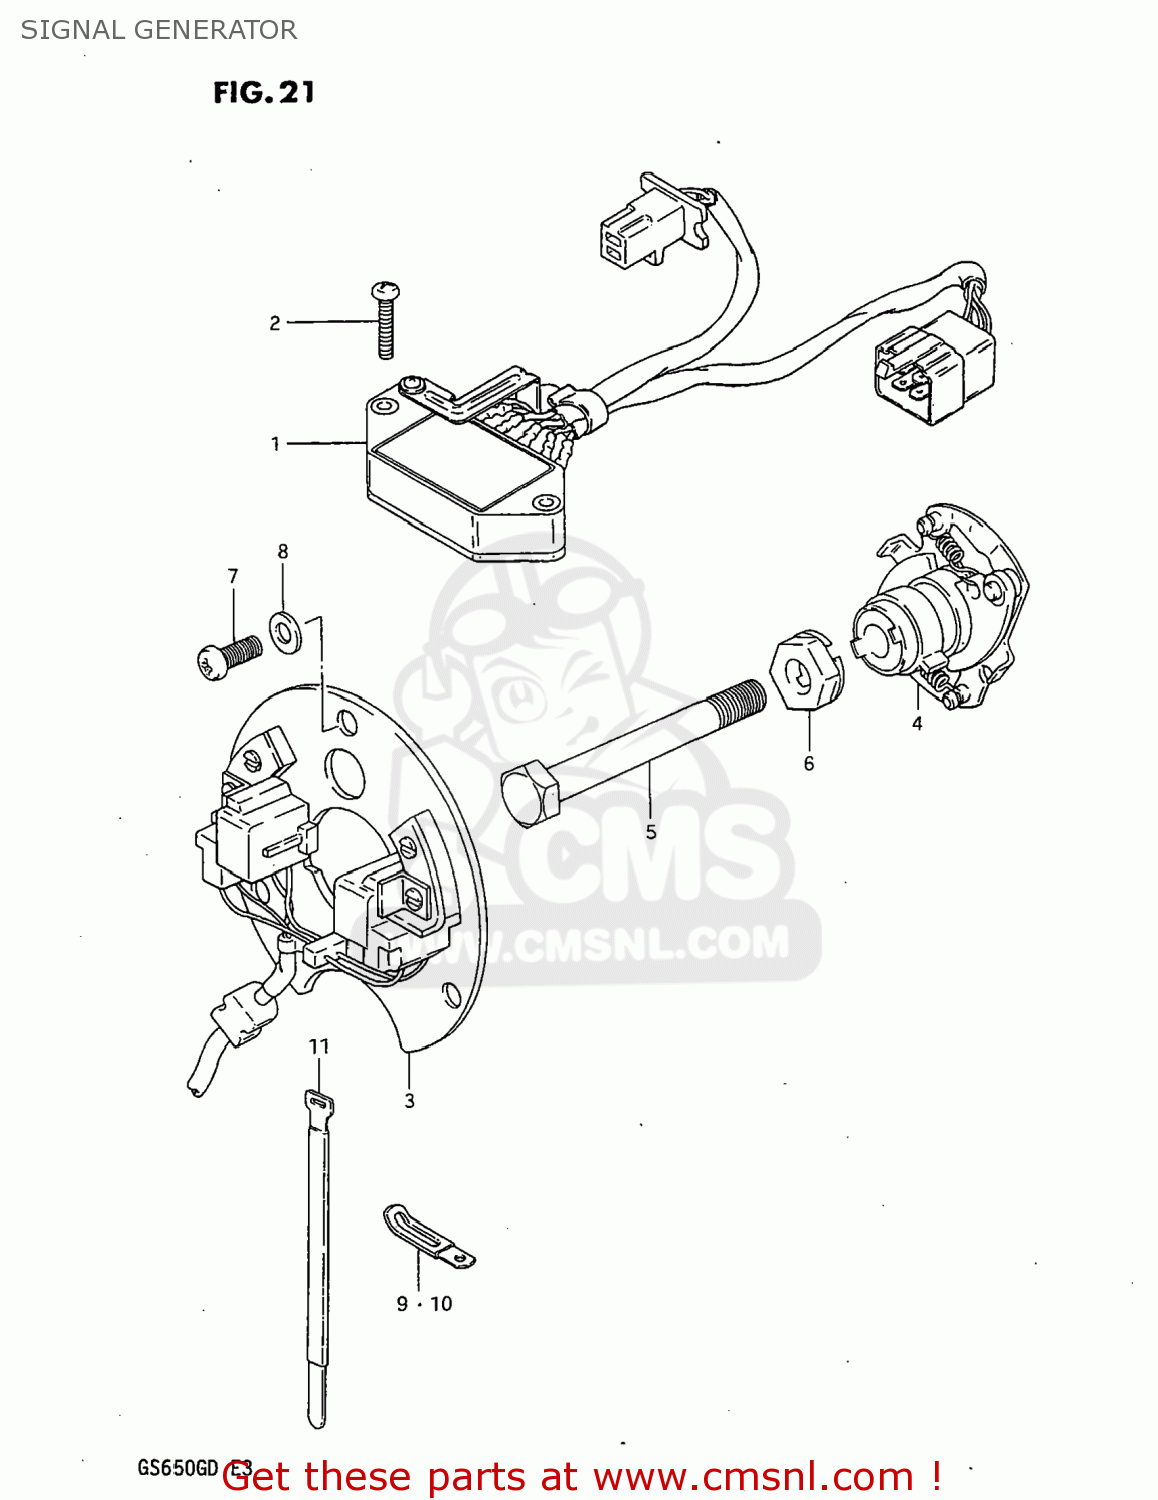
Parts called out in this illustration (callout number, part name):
1	IGNITER UNIT ASSEMBLY
2	SCREW
3	SIGNAL GENERATOR ASSEMBLY
4	GOVERNOR ASSEMBLY
5	BOLT
6	WASHER
7	SCREW(5X12)
8	WASHER
9	CLAMP L:35
10	CLAMP
11	CLAMP
